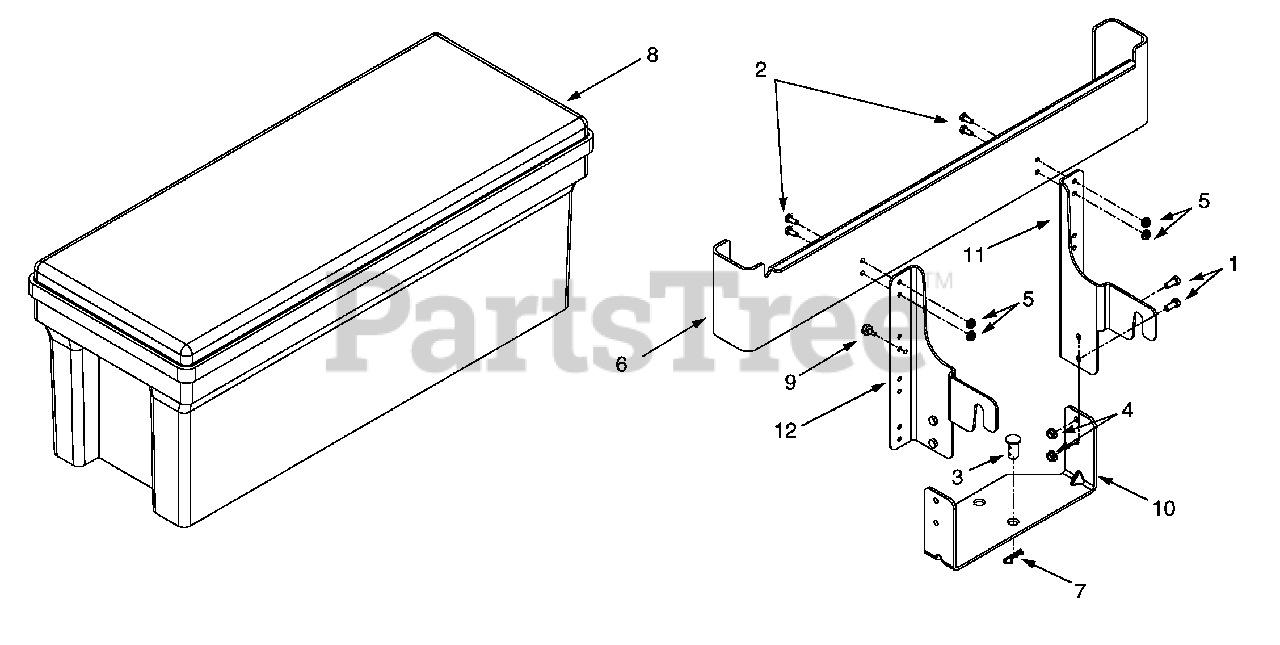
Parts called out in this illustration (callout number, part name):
1	Hex Cap Screw, 5/16-18 x .75
2	Hex Cap Screw, 1/4-20 x .62
3	Clevis Pin
4	Hex Flange Lock Nut, 5/16-18
5	Hex Flange Lock Nut, 1/4-20
8	Plastic Tool Box
9	Bumper, .62 Dia. x .3
